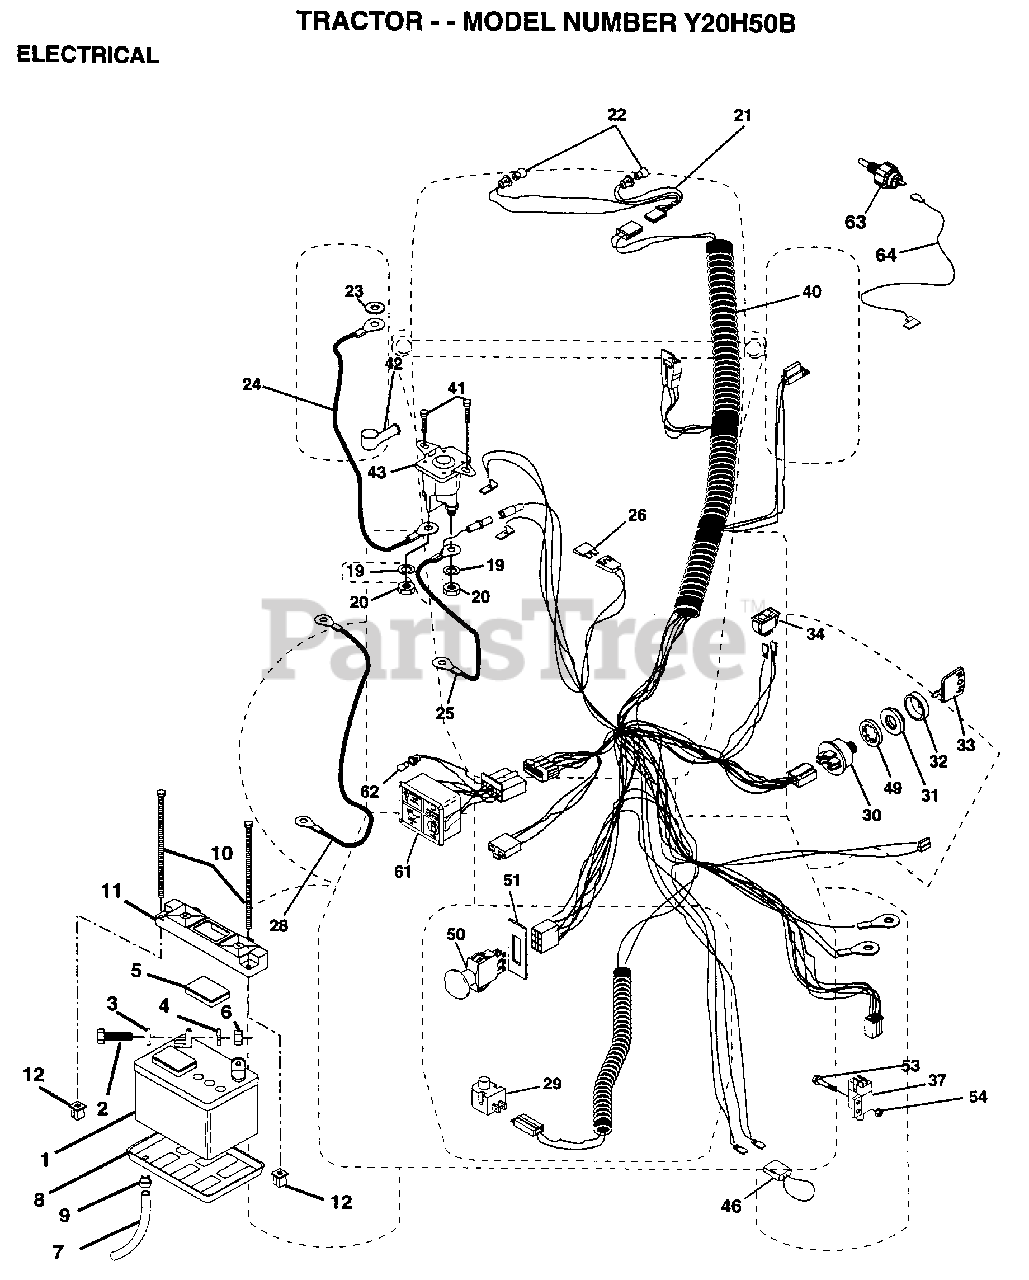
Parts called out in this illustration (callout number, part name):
2	BOLT LT
3	LOCKWASHER
4	WASHER
8	TRAY T, BATTERY
9	HOSE CLAMP T
20	NUT
21	"HARNESS,LIGHT SOC"
22	HEADLAMP BULB
24	CABLE T, BATTERY
25	CABLE.6GA.12.5.
26	FUSE HYT
28	CABLE T
29	SWITCH SEAT *SUBS/2*
32	COVER KEY SWITCH
33	KEY MLD GEN DELTA
34	SWITCH LT
37	SWITCH INTERLOCKT (2 2)
40	HARNESS.IGN.GT.EL
41	SCREW
46	PROTECTION LOOP
49	LOCKWASHER
51	RING RETAIN PTO
53	SCREW
54	"NUT,KEPS"
61	LIGHT.PKG.ASM.
63	SWITCH OIL KOHLER
64	WIRE LEAD KOHLER
